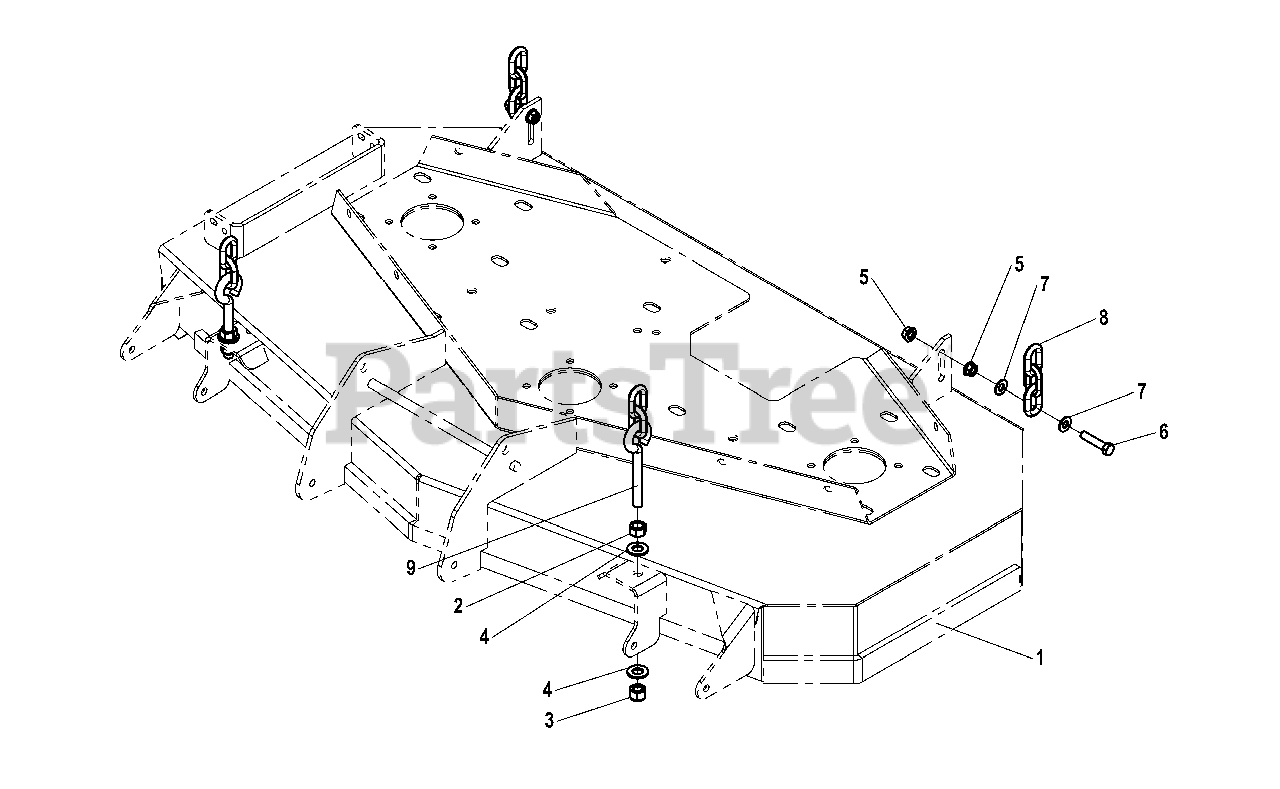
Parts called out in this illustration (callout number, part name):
1	MOWER DECK
2	NUT, 1/2-13 Hex
3	NUT, 1/2-13 Hex Nylon Lock
4	WASHER, 1/2" SAE
5	NUT, 3/8-16 Hex Large Serrated Flange
6	BOLT, 3/8-16 X 1-3/4"
7	WASHER 3/8" SAE
8	CHAIN, 5/16" GD30, 3 LINKS
9	HANGER, FRONT DECK - 2 LINK, 5.5" EB
